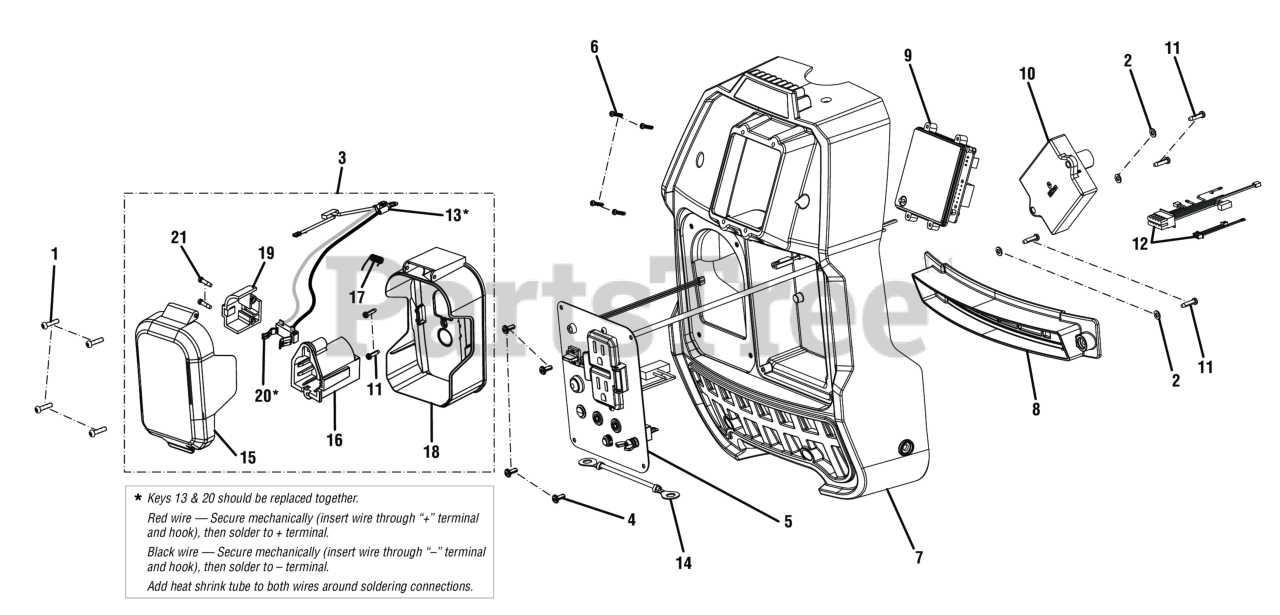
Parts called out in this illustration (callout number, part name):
1	Screw (M4 x 16 mm, T25 Torx Pan Hd.)
2	Washer (OD9 x ID4.4 x 1t)
3	Battery Housing Assembly
4	Screw w/Washer (M4 x 10 mm, T20 Torx Button Hd.)
5	Faceplate Assembly
6	Screw (#4-20, T10 Torx Pan Hd.)
7	Front Cover
8	Air Guide
9	GenControl Assembly
10	Auto-Choke Module
11	Screw (M4 x 16 mm, T20 Torx Socket Pan Hd.)
12	GenControl Wiring Harness
13	Internal Wire Assembly
14	Ground Wire
15	Battery Compartment Cover
16	Base (Battery Connect)
17	Torsion Spring
18	Battery Compartment Base
19	Press Cover (Battery Connect)
20	Plate (Battery Connect)
21	Screw (M3.5 x 12 mm, T10 Torx Pan Hd.)
